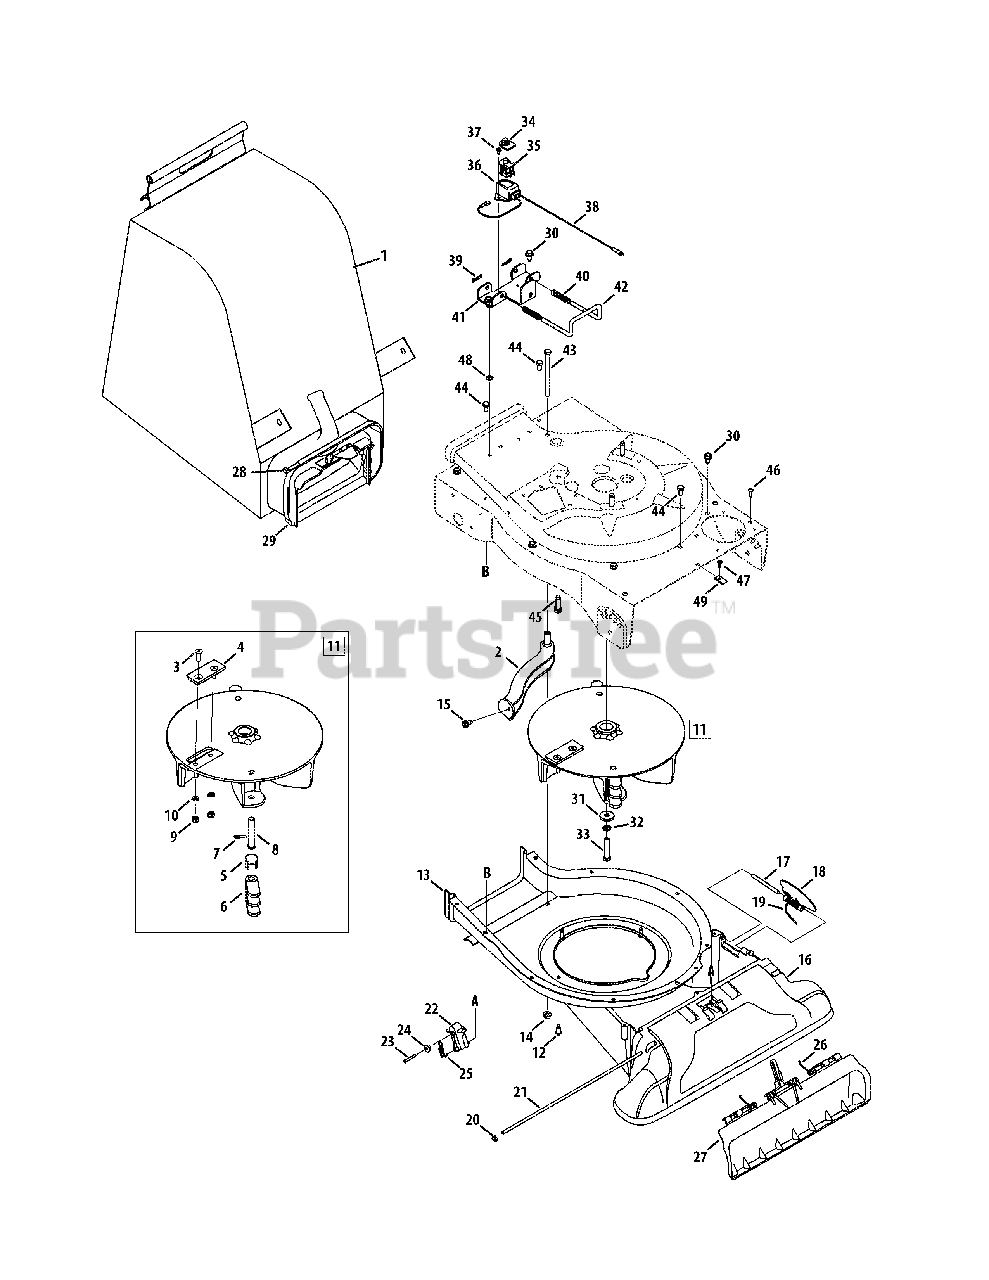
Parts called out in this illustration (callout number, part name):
1	Bag Assembly
2	Screen Assembly
3	Hex Screw 5/16-24 x 1.0
4	Chipper Blade
5	Pin Clip
6	Flail
7	Spiral Pin
8	Clevis Pin
9	Lock Nut, 5/16-24
10	Lock Washer, 5/16
11	Impeller Assembly
12	Shoulder Screw, #12-24 x.30 x.46
13	Lower Flail Housing
14	Flange Lock Nut 5/16-18
15	Screw, 5/16-18 x.500
16	Nozzle, Blk (Incl. Ref. #17-27)
17	Hinge Pin
18	Base Adapter Door
19	Torsion Spring
20	Cap Speed Nut 1/4
21	Pivot Rod
22	Nozzle Door Lever, Red
23	Hex Screw, #8-18 x 1.25
24	Shoulder Spacer
25	Extension Spring
26	Nozzle Door Torsion Spring
27	Nozzle Door
28	Bag
29	Chute Assembly
30	Hex Index Screw, 5/16-12 x.750
31	Flat Washer.375 ID x 1.25 OD
32	Lock Washer 3/8
33	Hex Cap Screw 3/8-24 x 2.0
34	Switch Cover
35	Safety Switch
36	Safety Switch Cover
37	Hex Washer Screw #10-16 x.50
38	Wire Harness
39	Cotter Pin
40	Compression Spring
41	Mounting Bracket
42	Lock Rod
43	Hex Cap Screw 5/16-18 x 4.5
44	Hex Cap Screw 5/16-18 x.625
45	Screw 3/8-16 x 1.00
46	Screw, #12-16 x.750
47	Screw #10 - 16 x.500
48	External L-Washer 5/16
49	Speed Nut
